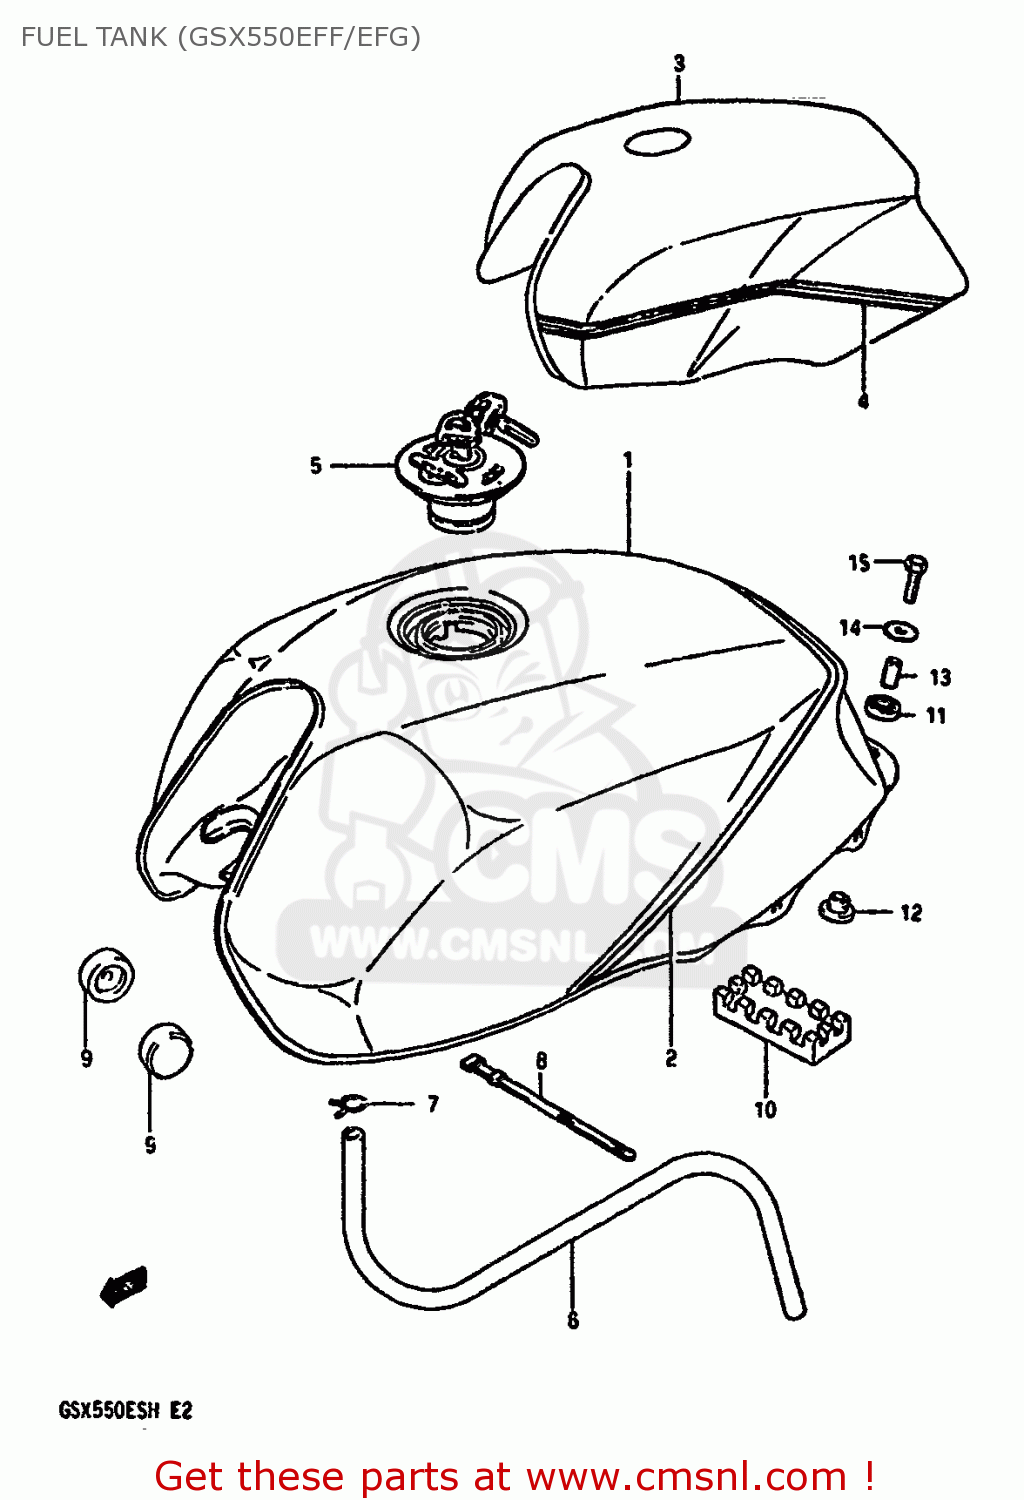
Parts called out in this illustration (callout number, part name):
1	TANK ASSY,FUEL
2	TAPE SET,FUEL TANK (BLACK)
3	TANK ASSY,FUEL
4	TAPE SET,FUEL TANK
5	CAP ASSY,FUEL TANK
6	HOSE,FUEL
7	CLIP
8	CLAMP(L:187)
9	CUSHION
10	CUSHION,FUEL TANK
11	CUSHION
12	CUSHION
13	SPACER (6.4X9X20)
14	WASHER (6.5X24X1.6)
15	BOLT
